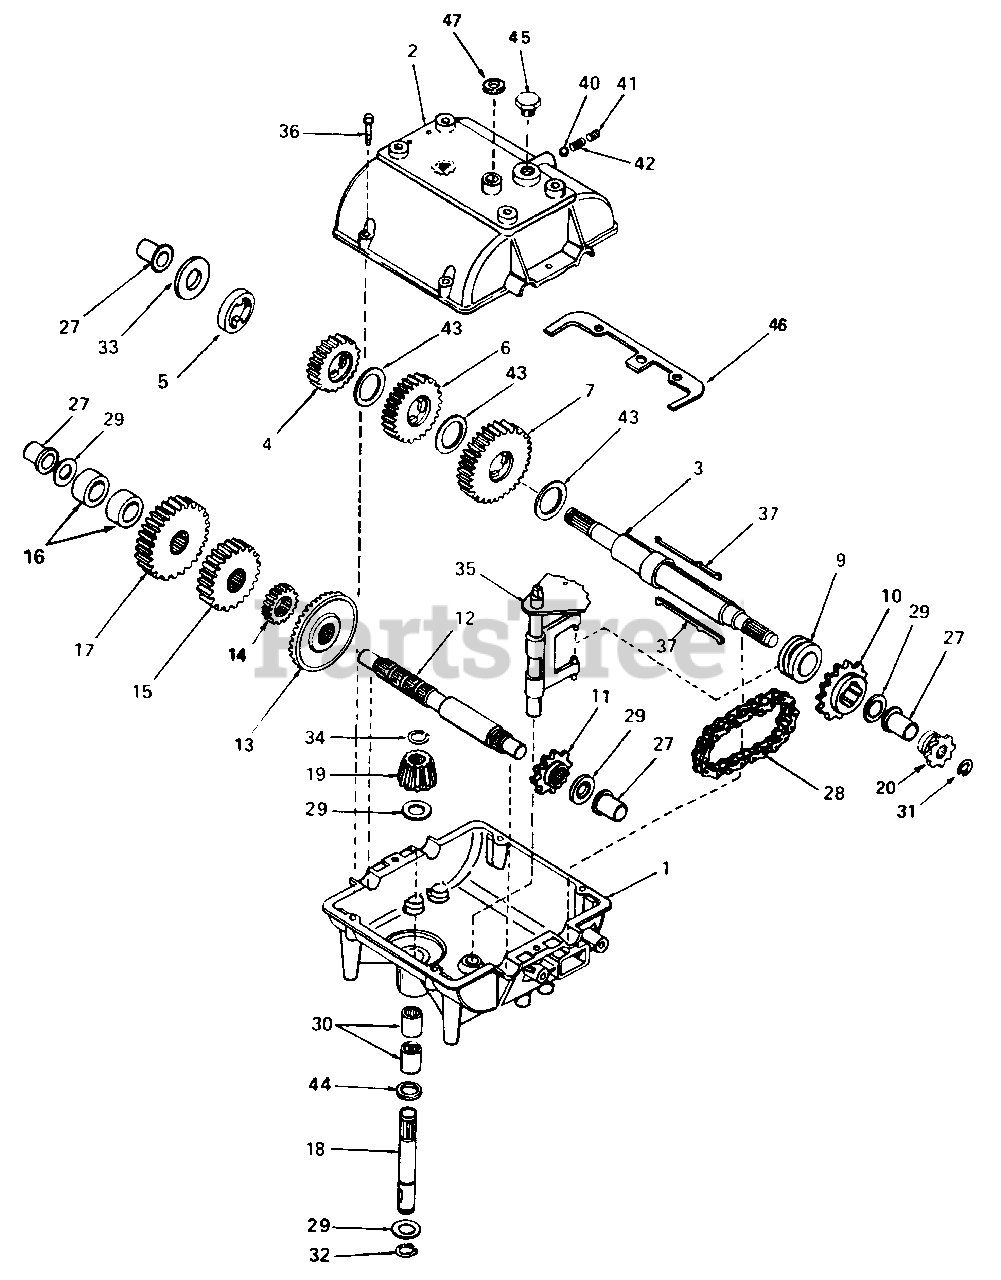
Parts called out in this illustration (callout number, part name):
1	CASE, Transmission
2	COVER, Transmission
3	SHAFT, Output & Brake
4	GEAR, Spur (20 teeth)
5	SPACER (1-3/8" O.D. x 1/8" I.D. x 3/8" thick)
6	GEAR, Spur (30 teeth)
7	GEAR, Spur (37 teeth)
9	COLLAR, Shift
10	SPROCKET (14 teeth)
11	SPROCKET (10 teeth)
12	SHAFT, Counter
13	GEAR, Bevel (42 teeth)
14	GEAR, Spur (12 teeth)
15	GEAR, Spur (20 teeth)
16	SPACER (1-1/8" O.D. x 3/4" I.D. x 3/8" thick)
17	GEAR, Spur (30 teeth)
18	SHAFT, Input
19	BEVEL PINION, Input
20	SPROCKET, (8 teeth)
27	BUSHING, Flanged
28	CHAIN, Roller (No. 41 chain, 22 links)
29	WASHER, Thrust
30	BEARING, Needle
31	RING, Retaining
32	RING, Retaining
33	WASHER, Thrust
34	RING, Retaining
35	ROD & FORK ASSY., Shift
36	SCREW, Fl. Hex Hd., Thread Forming, 1/4-20 x 1-1/4
40	BALL, Steel, 5/16"
41	SCREW, Set, 3/8-16 x 3/8
43	WASHER, Thrust
45	PLUG, Threaded
47	SEAL, Square Cut
